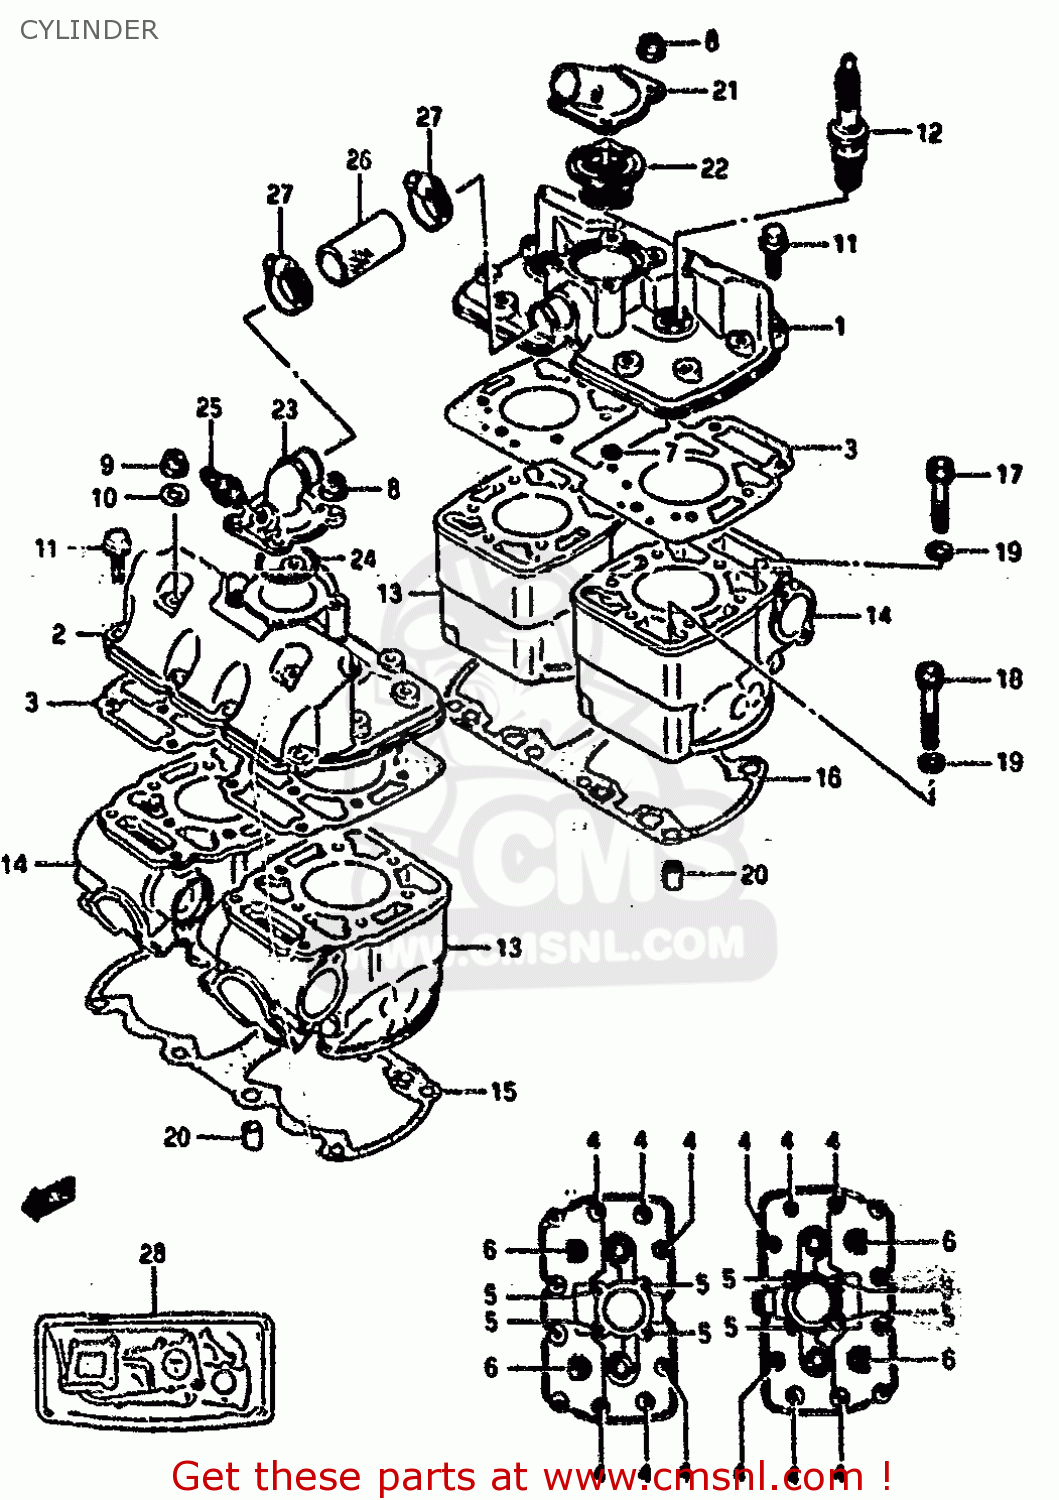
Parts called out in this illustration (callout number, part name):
1	HEAD,CYLINDER REAR
2	HEAD,CYLINDER FRONT
3	GASKET,CYLINDER HEAD (NAS)
4	STUD BOLT (L:36)
5	STUD BOLT
6	STUD BOLT (L:49)
7	O RING(D:1.9,ID:7.8)
8	NUT 8MM
9	NUT ,8MM
10	WASHER (8.2X24X1.6)
11	BOLT
12	SPARK PLUG B9ES
13	CYLINDER NO.1
14	CYLINDER NO.2
15	GASKET,CYLINDER FRONT (MCA)
16	GASKET,CYLINDER REAR (MCA)
17	BOLT
18	BOLT
19	WASHER(8.5X14X1.6)
20	PIN
21	COVER,THERMOSTAT
22	THERMOSTAT,WATER
23	CONNECTOR,CYLINDER HEAD HOSE
24	O RING(D:2.4,ID:43.2)
25	GAUGE, WATER TEMP
26	HOSE,CYLINDER HEAD JOINT
27	CLAMP
28	GASKET SET (MCA)
